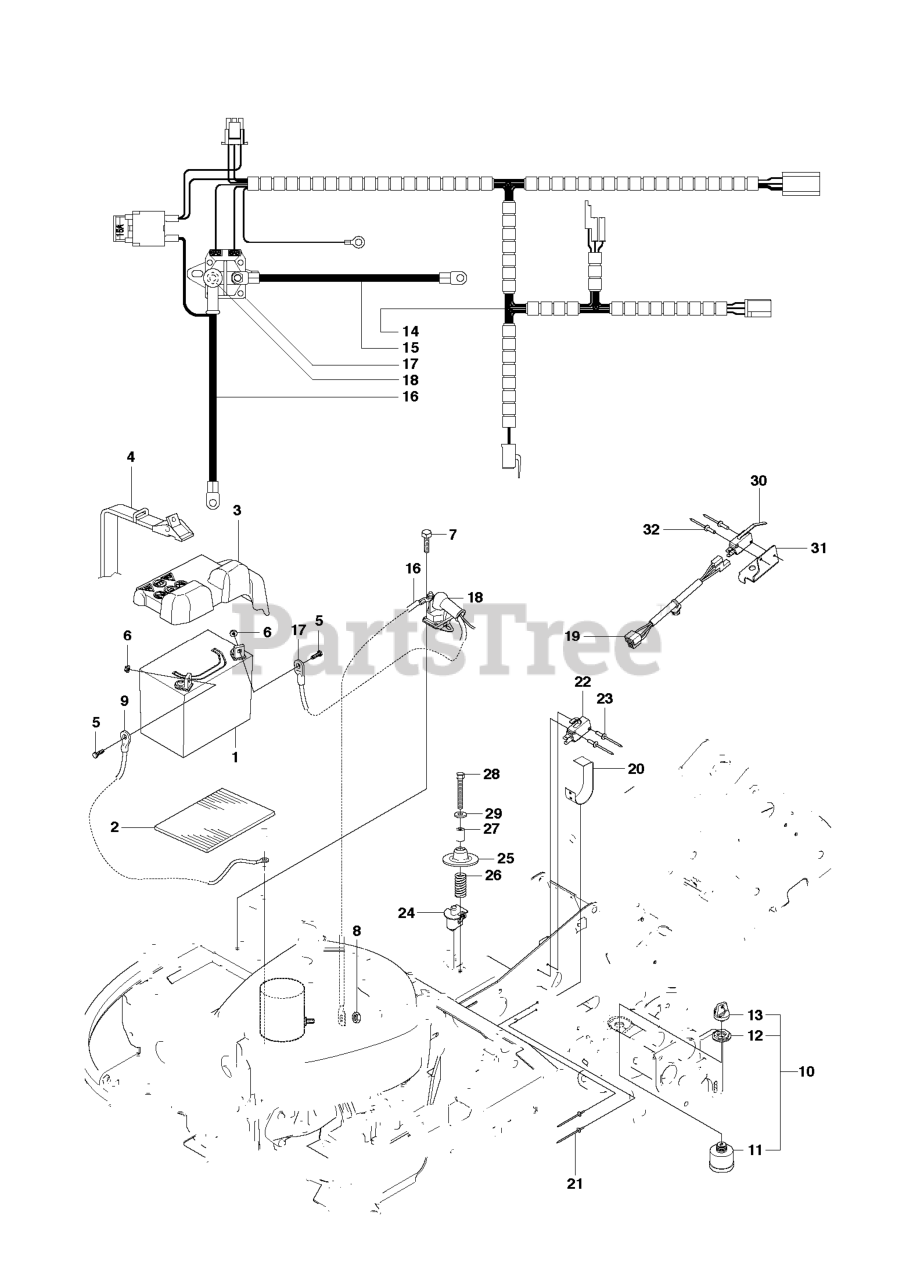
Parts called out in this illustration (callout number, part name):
5	SCREW EHHM
10	IGNITION SWITCH
11	IGNITION SWITCH
13	IGNITION KEY
19	WIRING
22	%BRAKER
27	SPACER TUBE
28	SCREW
29	WASHER BRB 8.4X17
30	RP MICRO SWITCH
